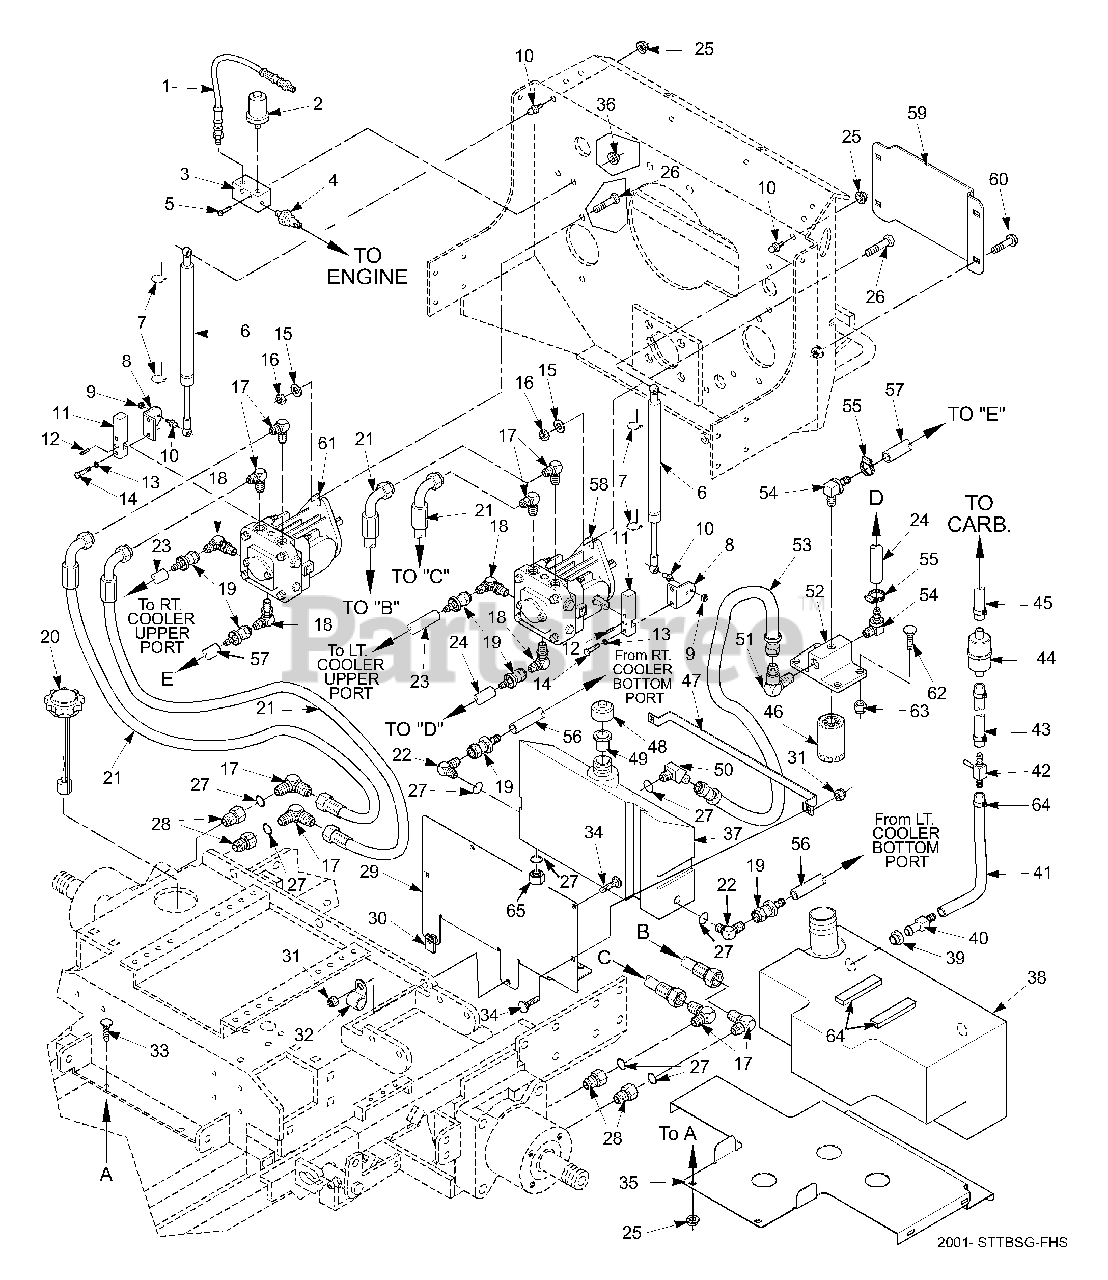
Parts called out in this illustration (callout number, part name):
1	Hose, Oil Pressure Sender
2	Oil Pressure Sender
3	Oil Manifold
4	Switch, Low Oil Pressure
5	Bolt, Hex Head 1/4-20 x 2"
6	Gas Damper
7	Spring Clip
8	Clamp Plate, Pump Control
9	Locknut, 5/16-18 CTR
10	Ball Stud
11	Block, Pump Control
12	Pin, Spring .210 x 1.0"
13	Lockwasher, 1/4 Spring
14	Bolt, Hex Head 1/4-20 x 1.50"
15	Flatwasher, 1/2 (.531 x .062 x .095)
16	Nut, 1/2-13 Elastic Stop
17	Elbow, 90 Degree, 7/8-14 THD
18	Elbow, 90 Degree,3/4-16 THD
19	Coupling, 3/4-16 THD
20	Cap, Fuel Tank W/Gauge
21	Hose Assembly, Wheel Motor
22	Elbow, 90 Degree, 9/16-18 JIC x 9/16 O-Ring
23	Hose, 3/8" ID. Pushlock - 25.0"
24	Hose, 3/8" ID. Pushlock - 10.25"
25	Nut, 5/16-18 Serrated Flange
26	Bolt, Hex Head 1/4-20 x 2.0"
27	O-Ring
28	Bushing, 7/8-14 JIC x 3/4-16 O-Ring
29	Support Bracket, Hydraulic Tank
30	U-Nut, 1/4-20
31	Nut, Hex Elastic Stop 1/4-20
32	Hose Clamp
33	Bolt, Carriage 5/16-18 x 3/4"
34	Bolt, Carriage 1/4-20 x 1.0"
35	Support Bracket, Fuel Tank
36	Nut, Hex 1/4-20 Serrated Flange
37	Oil Reservior Assembly
38	Fuel Tank Assembly
39	Bushing
40	Hose Fitting
41	Fuel Hose, 1/4" ID. - 10"
42	Valve, Shutoff
43	Fuel Hose, 1/4" ID. - 2"
44	Fuel Filter
45	Fuel Hose To Carb.
46	Oil Filter
47	Strap, Hydraulic Tank
48	Cap, Hydraulic Tank
49	Insert, Filler Neck
50	Elbow, 45 Degree 3/4-16 JIC x 3/4-16 O-Ring
51	Elbow, 45 Degree 1/2 NPT x 3/4 JIC
52	Oil Filter Base
53	Hose Assembly, (Hydro Tank to Filter Base)
54	Elbow, 90 Degree-1/4 NPT x 3/8 Hose
55	Clamp, Hose 1/2"
56	Hose, 3/8 ID. Pushlock - 14.50"
57	Hose, 3/8 ID. Pushlock - 38.0"
58	Pump, BDP-21L-305 LH
59	Rear Cover
60	Bolt, Carriage 5/16-18 x .75"
61	Pump, BDP-21L-403 RH
62	Bolt, Carriage 5/16-18 x 1.0"
63	Nut, Hex Elastic Stop 5/16-18
64	Pad, Rubber
65	Plug, 3/4-16" O" Ring
